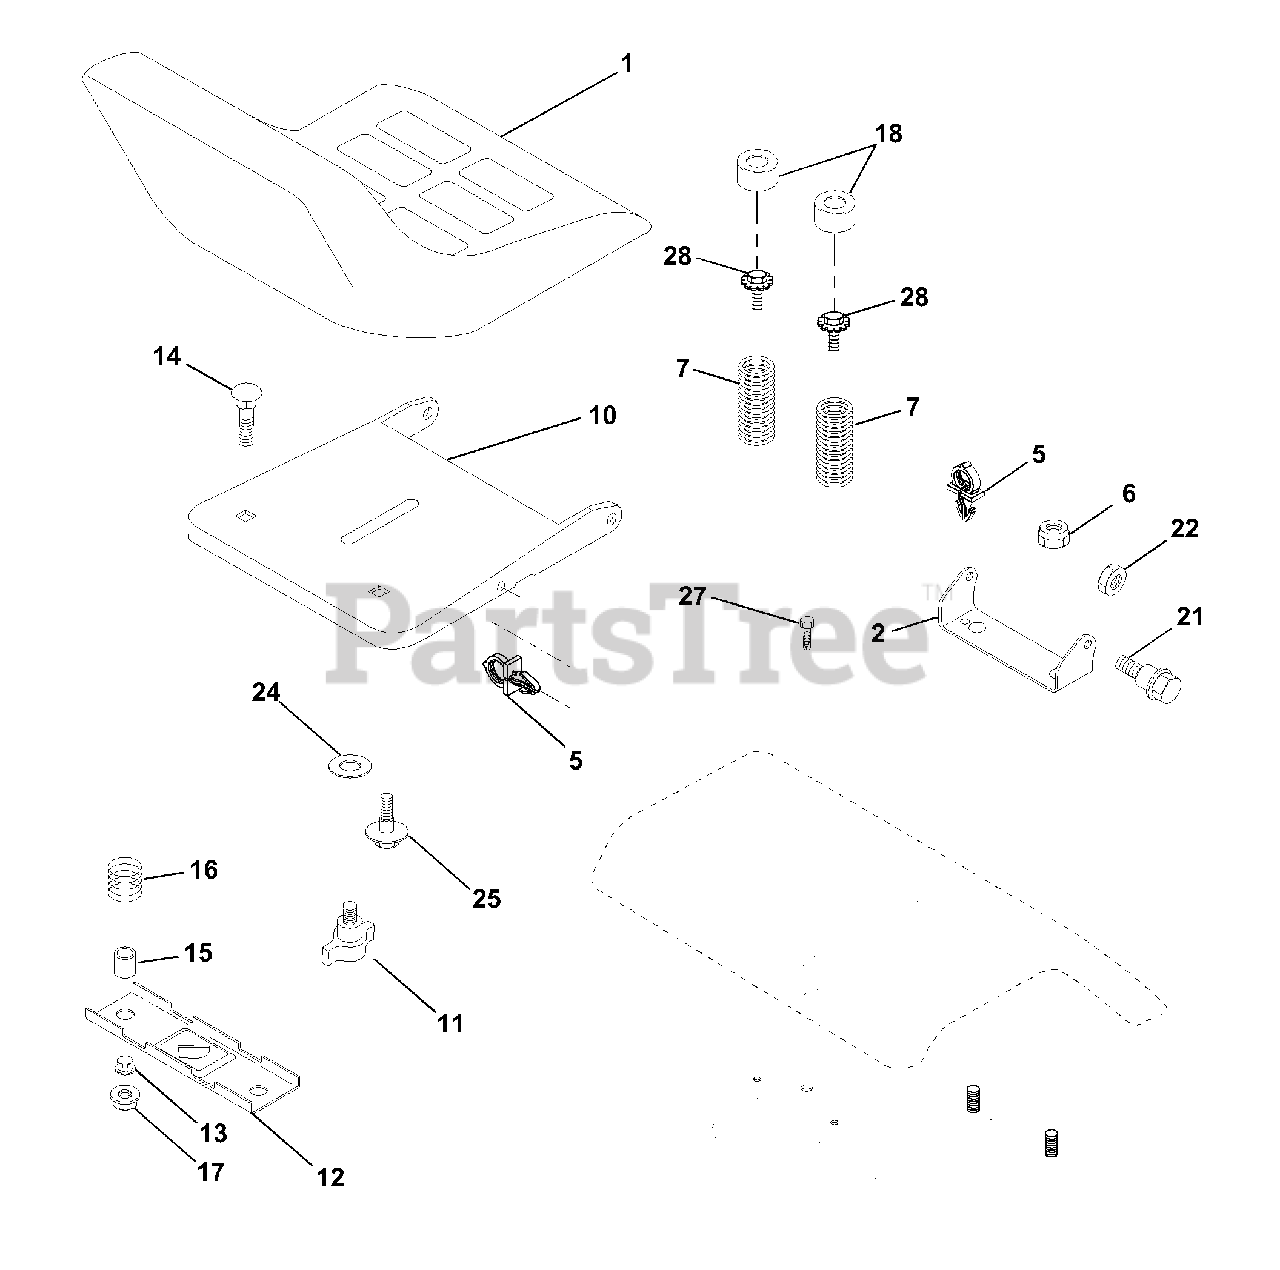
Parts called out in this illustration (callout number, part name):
1	Seat
2	Pivot Bracket, Seat
5	Clip, Push-in Hinged
6	Nut Crown Lock 3/8-16 Unc Blk D
7	Spring, Seat
10	Pan, Seat
11	Knob, Seat
12	Bracket, Switch Mounting
13	Bushing, Snap, Black, Nylon
14	Bolt, Carriage 1/4-20 x 1-1/2
15	Spacer, Split .28 x .96
17	Locknut, Flange 1/4 Grade 5
18	Cap Spring Seat Blk 1.75 x 1.0
21	Bolt, Shoulder 5/16-18 Unc -2A
22	Nut, Crownlock 5/16-18
24	Washer 17/32 x 1-3/16 x 12 Gauge
25	Bolt, Shoulder 5/16-18 x .62
27	Screw Thdrol 3/8-16 x 3/4
28	Bolt 5/16-18 UNC x 3/4 w/Sems
